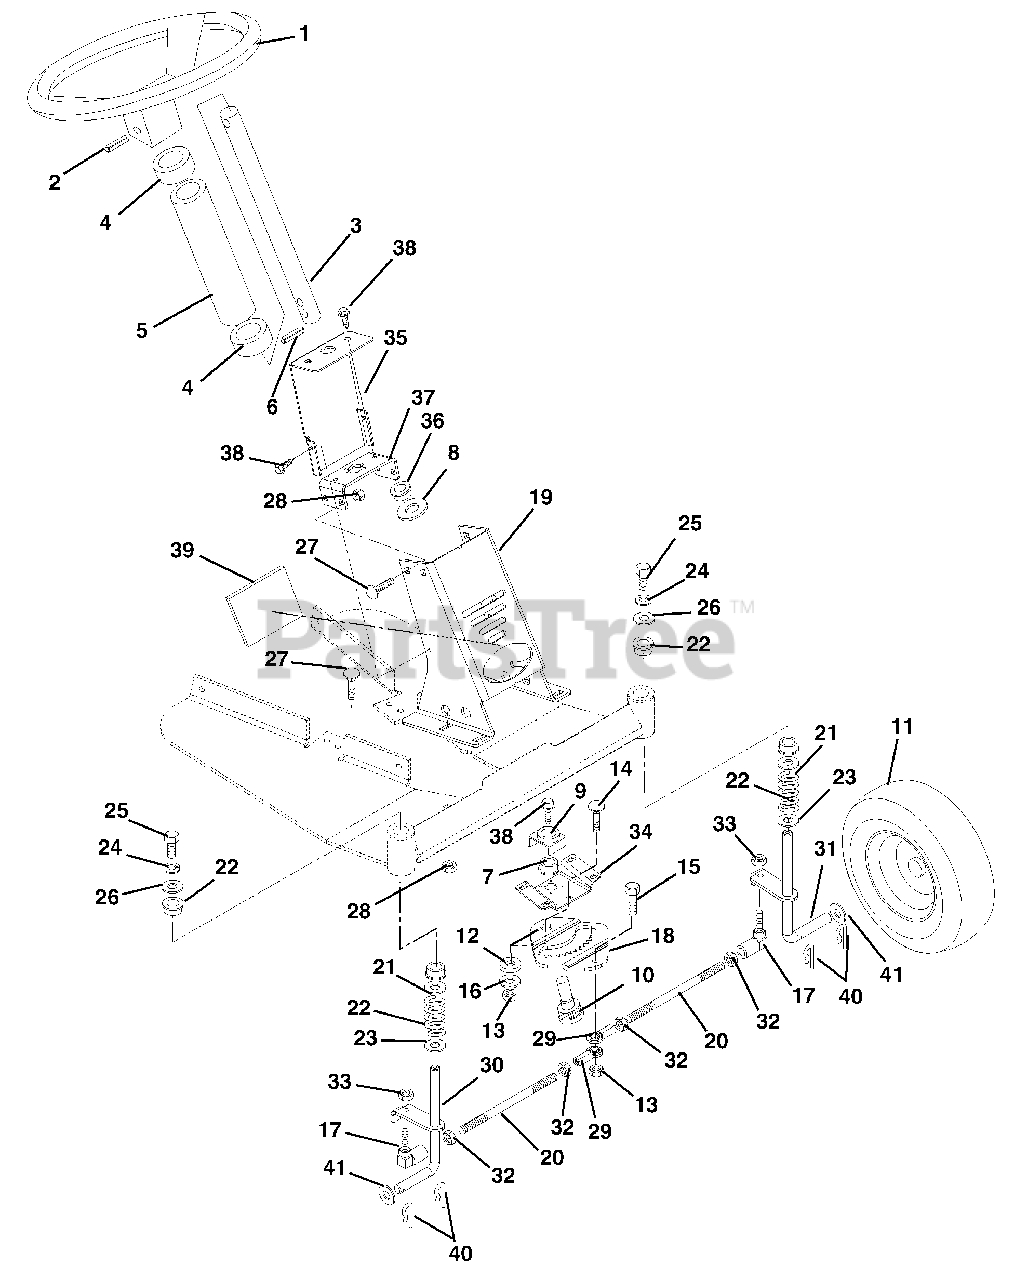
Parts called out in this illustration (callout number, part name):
1	Steering Wheel 13 Inch
2	Pin, Roll .25 x 1.75
3	Steering Shaft
6	Pin, Roll .188 x .75
7	Bushing, Flange .625 x 1.156 x .375
8	Washer, Hardened Steel .515 x .97 x .062
9	Retaining Plate1
10	Pinion
11	Tire/Wheel Assembly
11	Tire 4.10/3.50 - 4
11	Bushing, Flange .75 x 1.38 x .75 x 1.557
12	Spacer, Steering Gear
13	Nut, Locking Top Flange .38-16
14	Bolt, Round Head Square Neck .38-16 x 1.00 Grade 5
15	Bolt-Hex .38-16 x 1.75 Grade 5
16	Washer, Flat Steel .406 x 1.375 x .135
17	Ball Joint
18	Steering Gear
19	Box, Steering
20	Steering Link
21	Spring, Suspension
22	Bushing 1.00 x .75 x 1.00
23	Washer-Flat-Steel .70 x 1.47 x .134
24	Washer, Locking .31 x .078 Regular
25	Bolt, Hex .31-18 x .75 Grade 5
26	Washer, Flat Steel .406 x 1.375 x .135
27	Bolt, Round Head Square Neck .38-16 x .75 Grade 5
28	Nut, Locking Top Flange .38-16
29	Rod End, .38 Right Hand
30	Weldment, Spindle Right Hand
31	Weldment, Spindle Left Hand
32	Nut, Jam .375-24
33	Nut, Locking Nylon .375-24 With Insert
34	Steering Gear Support
35	Bracket, Steering Column
36	Bushing, Flange
37	Support, Steering Column
38	Screw, Tapping .312-18 x .50 Hex Washer Head
39	Cover, Light
40	Pin, Spring Clip
41	Washer, Flat Steel .755 x 1.375 x .062
